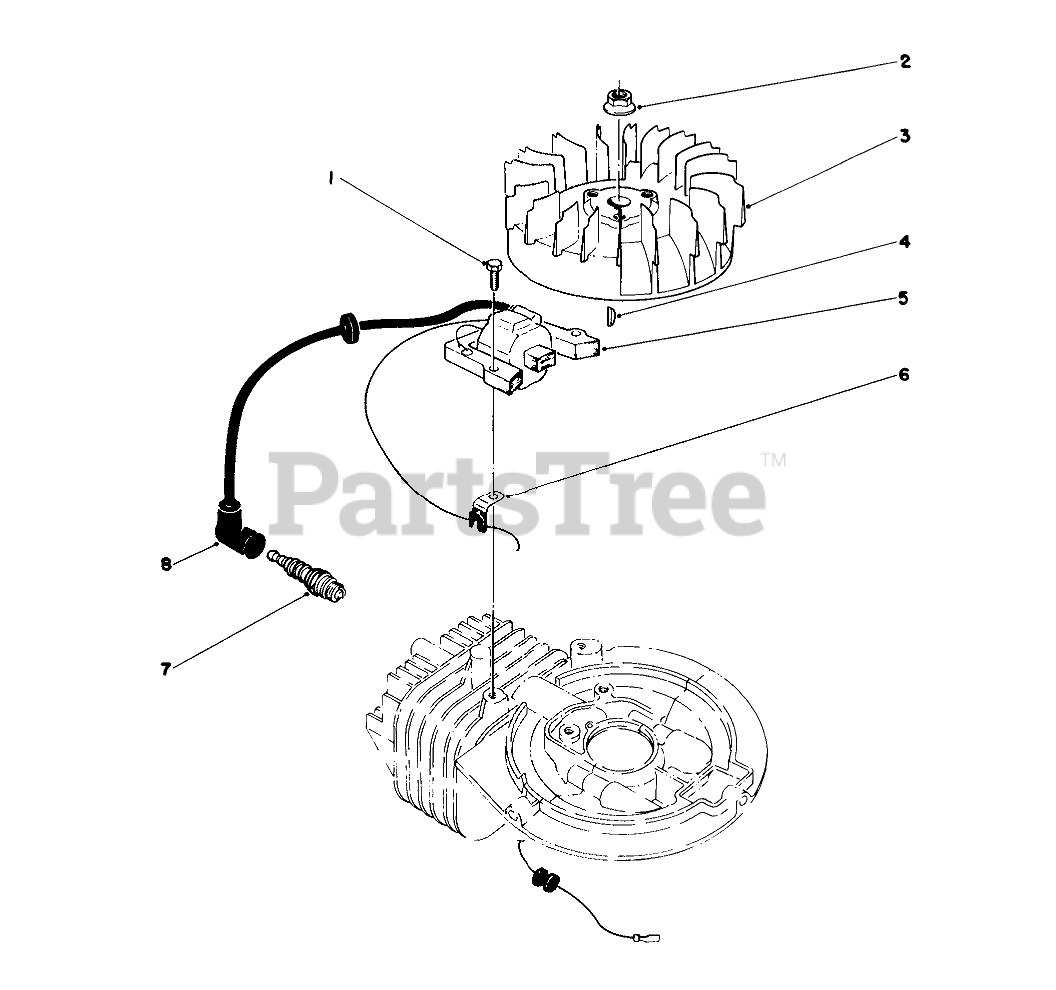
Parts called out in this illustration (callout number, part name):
1	SCREW
3	FLYWHEEL
5	COIL-MAGNETO
6	CLAMP
7	Sparkplug
8	CAP-SPARKPLUG
